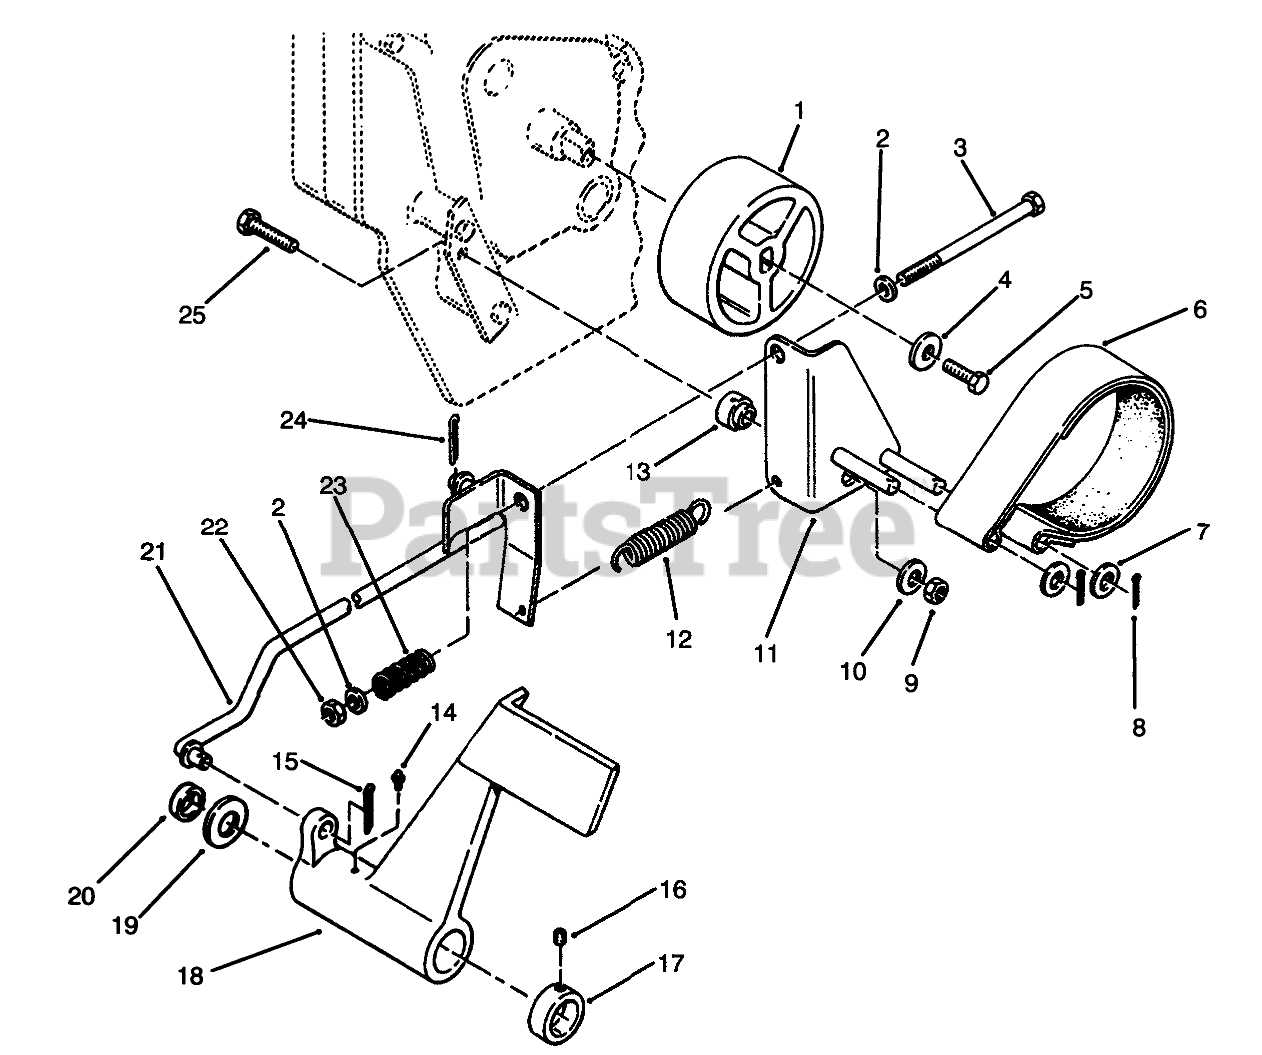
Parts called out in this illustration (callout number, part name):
1	DRUM-BRAKE
2	WASHER-FLAT
3	SCREW-HH
4	WASHER
5	SCREW-HH, LOCK
6	ASSY-BRAKE BAND
7	WASHER-FLAT
8	PIN-COTTER
9	NUT-LOCK, NI
10	WASHER-FLAT
11	WA-BRAKE PIVOT B
12	SPRING
13	BUSHING-BRAKE PIVOT
14	FITTING-GREASE
15	PIN-COTTER
16	SCREW-HSH
17	COLLAR
18	Pedal-Brake
19	WASHER
20	SPACER-OUTER
21	ASY BRAK RD WAR
22	NUT-LOCK, NI
23	SPRING-COMPRESSION
24	Hairpin
25	SCREW-HH
